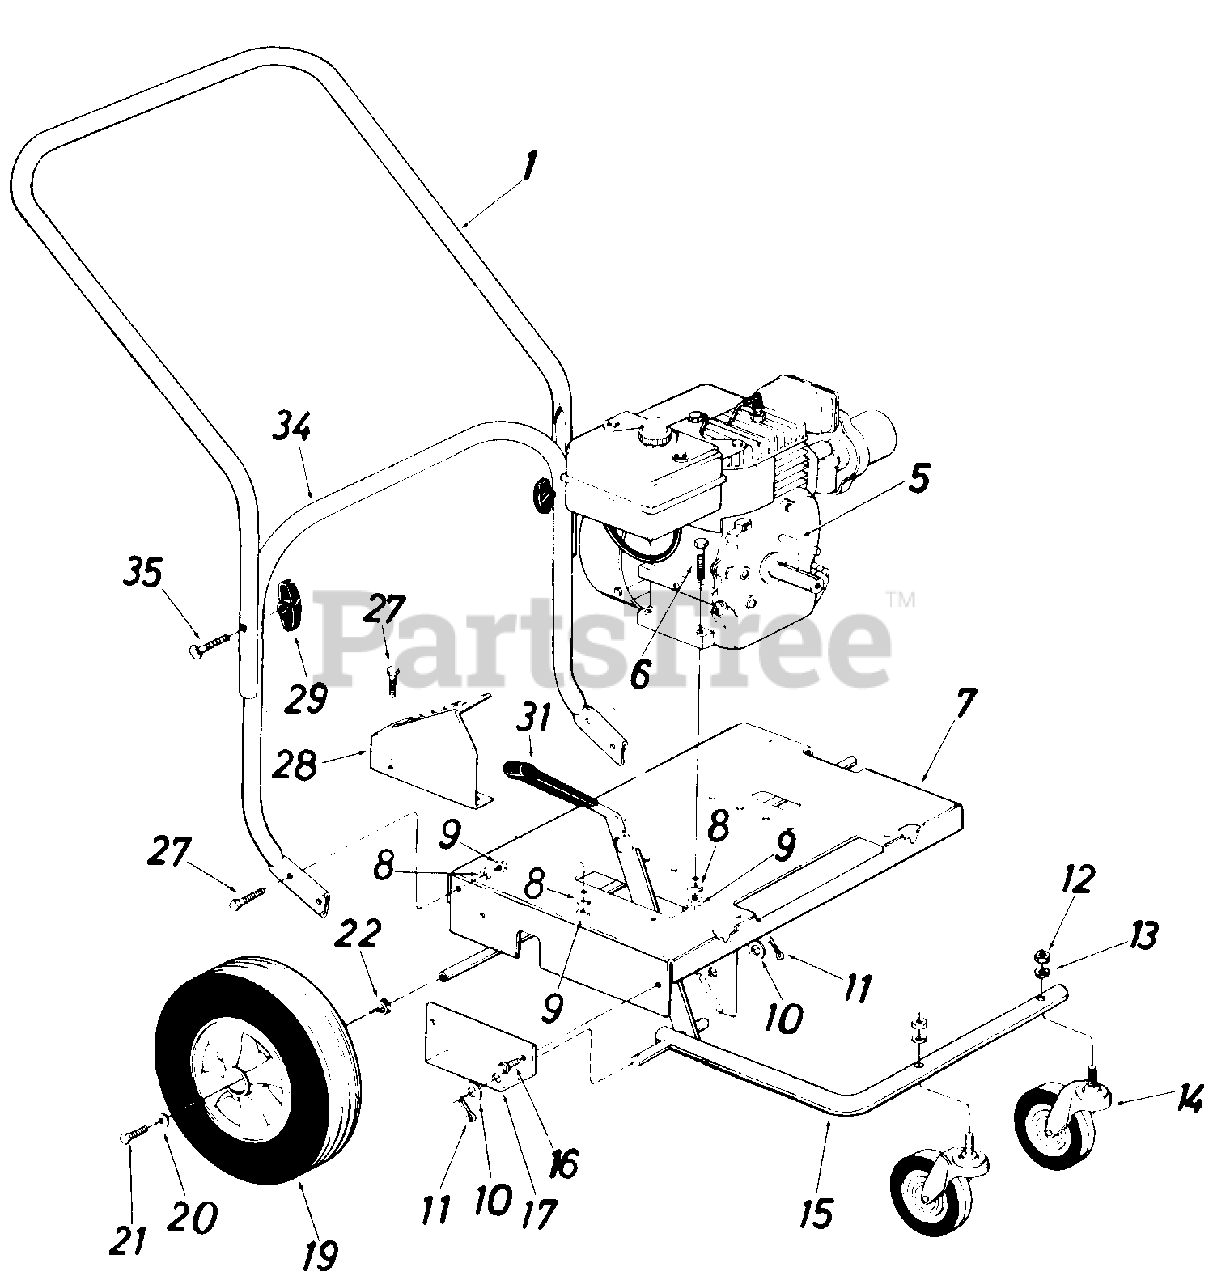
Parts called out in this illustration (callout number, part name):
1	Upper Handle
5	Sq. Key 1/4 x 2.00 Lg.*
6	Hex Bolt 5/16-18 x 1.50" Lg.*
7	Engine Mounting Frame Ass'y.
8	L.-Wash. 5/16" I.D.*
9	Hex Nut 5/16-18 Thd.*
10	Fl.-Wash. .63" I.D. x 1.25" O.D.
11	Cotter Pin 5/32" Dia. x 1.25" Lg.*
12	Hex Nut 1/2-13 Thd.*
13	L.-Wash. 1/2" I.D.*
14	Swivel Caster Wheel 5" Dia. x 1.25"
15	Caster Arm Ass'y.
16	Hex Wash. Hd. "AB" Tap Scr. 5/16" x .75"
20	Fl.-Wash. 34" I.D. x .87" O.D.
21	Hex Locking Bolt 5/16-24 x .62" Lg.
22	Fl.-Wash.
27	Hex Bolt 5/16-18 x .75" Lg.*
28	Index Plate
29	Hand Knob
31	Fl.-Grip Vinyl
34	Lower Handle
35	Carriage Bolt 5/16-18 x 2.0" Lg.
